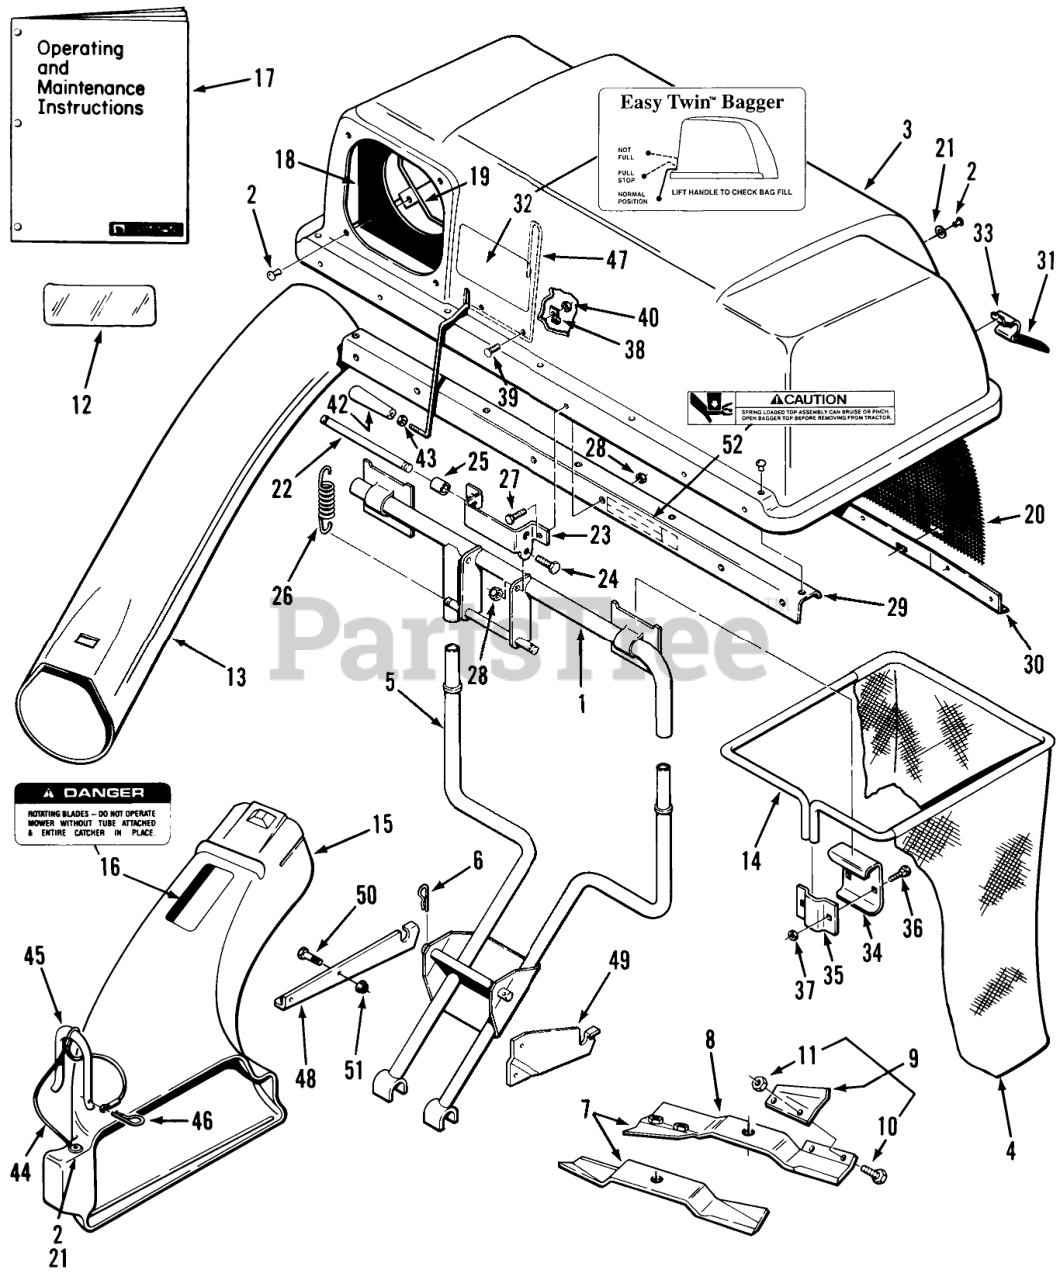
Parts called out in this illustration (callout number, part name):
1	FRAME ASM
2	RIVET-BLIND
3	TOP-BAGGER
4	Bag
5	WLDMT-QUICK ATTAC B
6	Hairpin
7	Blade Kit (includes LH blade, RH blade with tabs)
8	High Lift Blade (includes item 9) RH side
9	Lift Tab Kit (includes items 10 & 11)
10	BOLT 5/16-18X5/8
11	NUT-LOCK 5/16-18
12	DECAL-OVERLAY
13	CHUTE-BAGGER (L)
14	Bag Frame
15	Discharge Elbow (includes items 16 & 44 installed)
16	DECAL-DANGER
17	Operating and Maintenance Instructions
18	Chute Seal
19	CLAMP-SEAL
20	SCREEN-BAGGER
21	Washer
22	PIN-SPRING
23	HINGE-BAG TOPB
24	Bolt
25	SPACER
26	SPRING-EXTENSION
27	BOLT
28	NUT
29	Bagger-Stiffener
30	SUPPORT-SCREEN B
32	Decal-Full Bag Test
33	Latch-Bag
34	Bag Hanger
35	Clamp
36	Bolt
37	Nut
39	Screw
40	Nut
42	HANDLE-TAPERED
43	Nut
44	LANYARD-ELBOW LATCH
45	LATCH-ELBOW
46	Hairpin Cotter
47	SERV ASSY-HOOD & PKG
48	SUPPORT-BAGGER R. B
49	SUPPORT-BAGGER L. B
50	HHCS
51	Nut
52	DECAL-CAUTION
